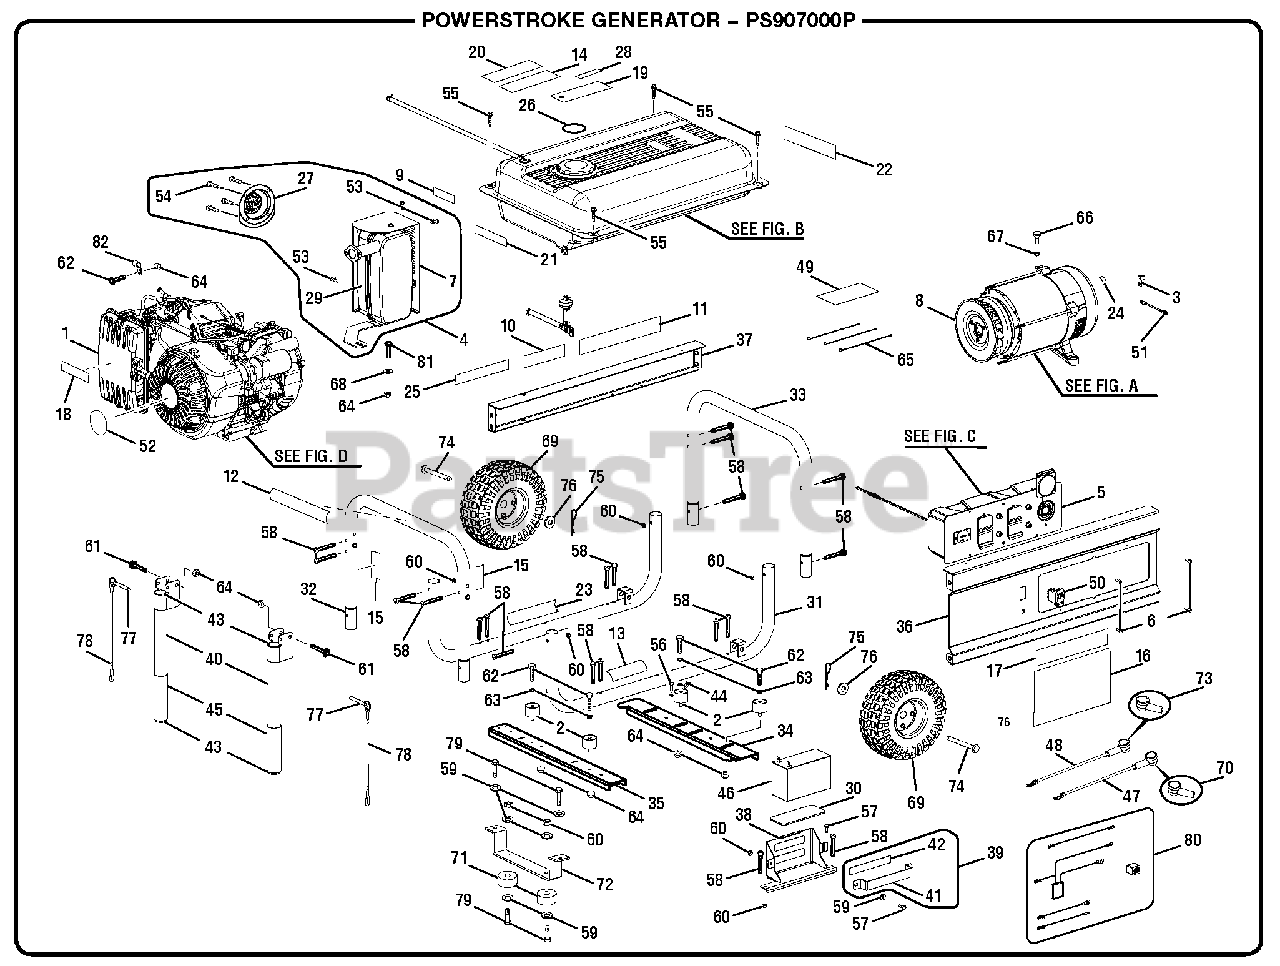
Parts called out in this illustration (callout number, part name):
1	Engine
3	Ground Lug
4	Muffler Assembly
5	Control Panel Assembly
6	Screw (6-20 x 3/8 in., Pan Hd.)
7	Heat Shield
8	Generator Head w/AVR
9	Starting Instructions Label
10	Hot Surface Label
11	Danger Label
12	Fire Danger Label
13	Engine Lubricant Label
14	Fuel Stabilizer Label (Spanish)
15	Locking Pin Label
16	Performance Label
17	Electric Start Label
18	Choke Label
19	Oil Hangtag
20	CPSC Label
21	Inquiries Label
22	Ground Warning Label
23	Combustion Warning Label
24	Ground Label
25	Fire Distance Label
26	Fuel Stabilizer Label
27	Spark Arrestor
28	E85 Label
29	Muffler w/Brackets
30	Gasket (Battery Tray)
31	Lower Frame Assembly
32	Left Frame Assembly
33	Right Frame Assembly
34	Crossbar (Generator Head)
35	Crossbar (Engine)
36	Front Panel
37	Back Panel
38	Battery Box
39	Battery Hold Down Bracket Assembly
40	Handle Assembly
41	Battery Retaining Bracket
42	Battery Bracket Gasket
43	End Cap (Handle Tube)
44	Bonding Wire
45	Handle Grip
46	Battery (9AH)
47	Battery Cable (Red)
48	Battery Cable (Black)
49	Rubber Sheet
50	Start Switch w/Lock
51	Ground Wire Assembly
52	Recoil Label
53	Bolt (M6 x 9 mm)
54	Screw (8-32 x 3/8 in., Pan Hd.)
55	Screw (1/4-14 x 1-1/4 in.)
56	Screw (#10-16 x 3/4 in.)
57	Screw (M6 x 16 mm, Hex Hd.)
58	Screw (M6 x 50 mm, T30 Pan Hd.)
59	Washer (ID6 x OD17 x 1.6t)
60	Lock Nut (M6)
61	Bolt (M8 x 55 mm, Hex Hd.)
62	Bolt (M8 x 35 mm, Hex Hd.)
63	Washer (M8)
64	Flange Nut (M8)
66	Bolt (M8 x 20 mm, Hex Hd.)
67	Star Washer (M8)
68	Washer (5/16 in)
70	Rubber Battery Cable Boot (Red)
72	Foot Bracket
73	Rubber Battery Cable Boot (Black)
75	Hitch Pin
76	Washer (1/2 in.)
77	Release Pin
79	Bolt (M6 x 25 mm, Hex Hd.)
80	Wiring Harness
81	Screw (M8 x 40 mm, Hex Hd.)
82	J-Clamp (1/3 in.)
